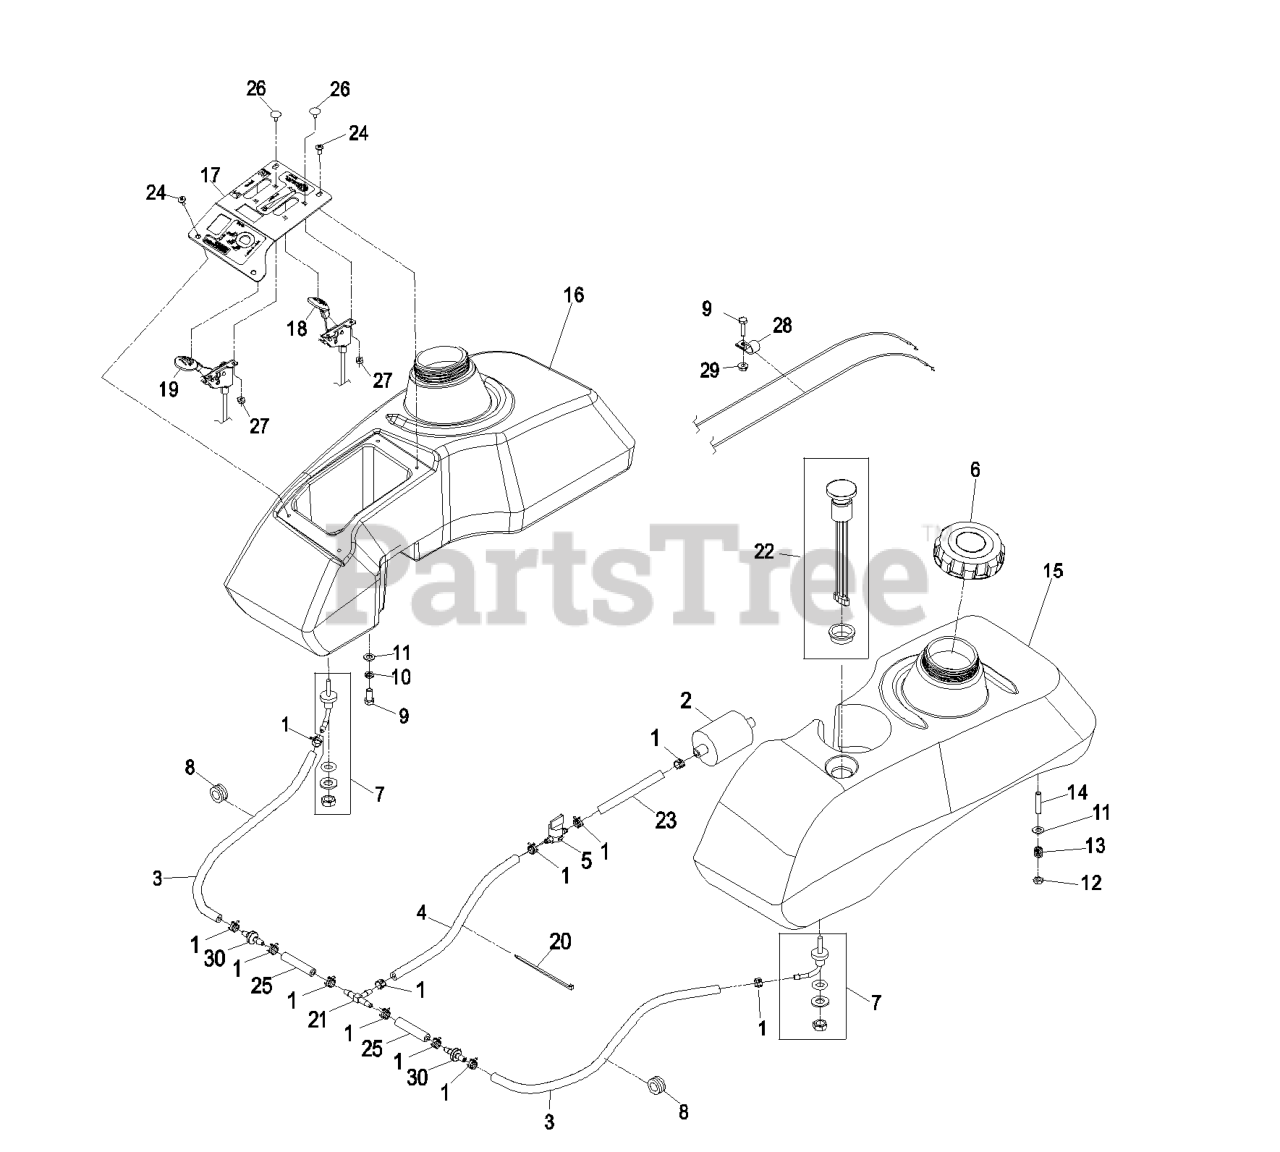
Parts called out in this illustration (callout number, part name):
2	Kohler Part No. 2405010 Fuel Filter
3	HOSE,FUEL
4	HOSE-FUEL
5	VALVE-FUEL
6	CAP-FUEL, GAS
7	FITTING-FUEL, BULKHEAD
8	GROMMET
9	SCREW-HH
10	WASHER-LOCK
11	WASHER-PLAIN
12	NUT-LOCK, NI
13	SPRING-TANK, FUEL
14	STUD
15	KIT,FUEL TANK LH LHP
16	ASM, LHP RH FUEL TANK S.O
17	PANEL,CONTROL W/DECALS
18	CONTROL-THROTTLE
19	CONTROL,CHOKE
20	TIE-PLASTIC
21	FITTING-TEE, BARBED
22	KIT, HP FUEL GAGE REPL.
23	HOSE-FUEL
24	SCREW-PPH
25	HOSE-FUEL
26	BOLT-CARR
27	NUT-LOCK, NI
28	CLIP-LOOM
30	VALVE-CHECK, FUEL
